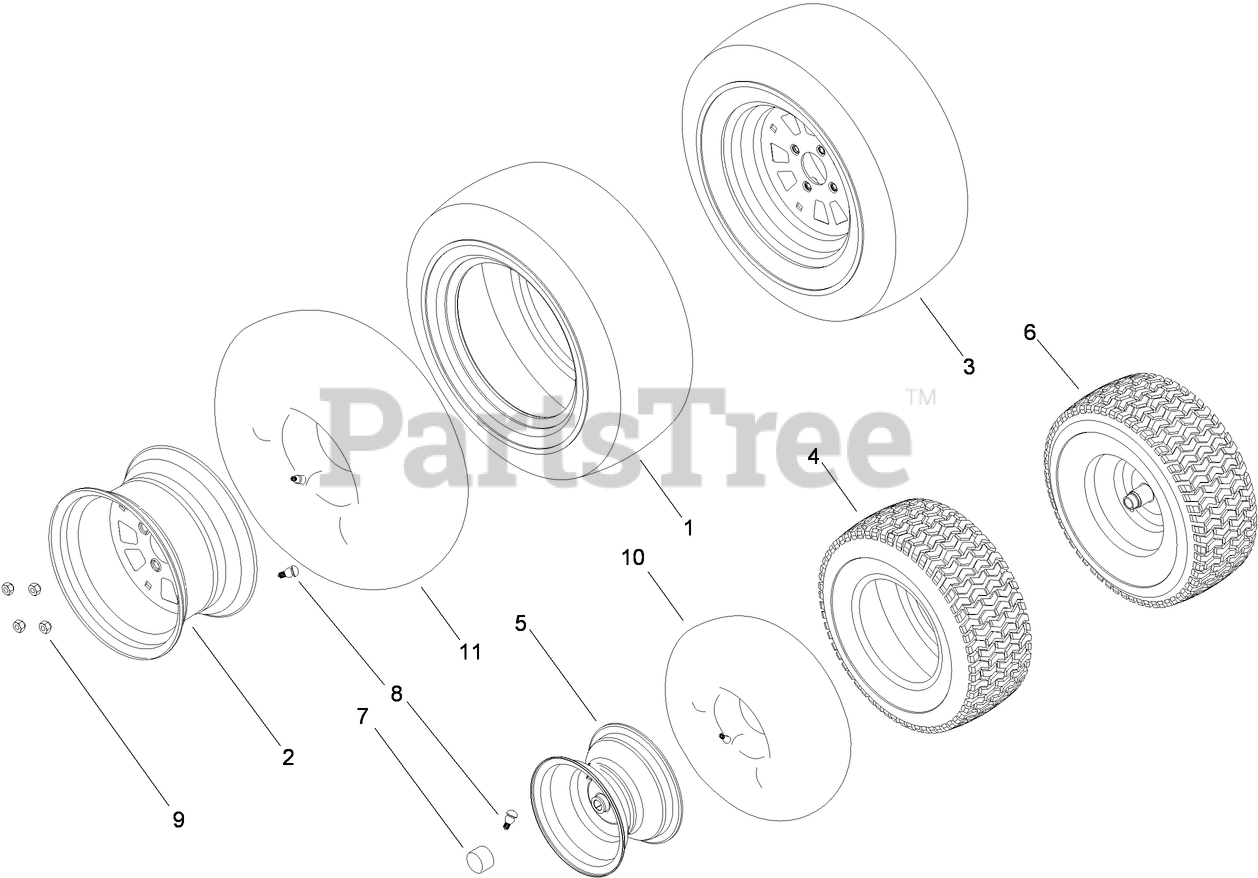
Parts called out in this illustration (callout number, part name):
1	TIRE-TURF
2	RIM ASM
3	WHEEL ASM
4	TIRE-TURF
5	RIM ASM
6	WHEEL ASM
7	CAP-HUB
8	VALVE-AIR, TUBELESS
9	NUT-LUG
10	TUBE-INNER
